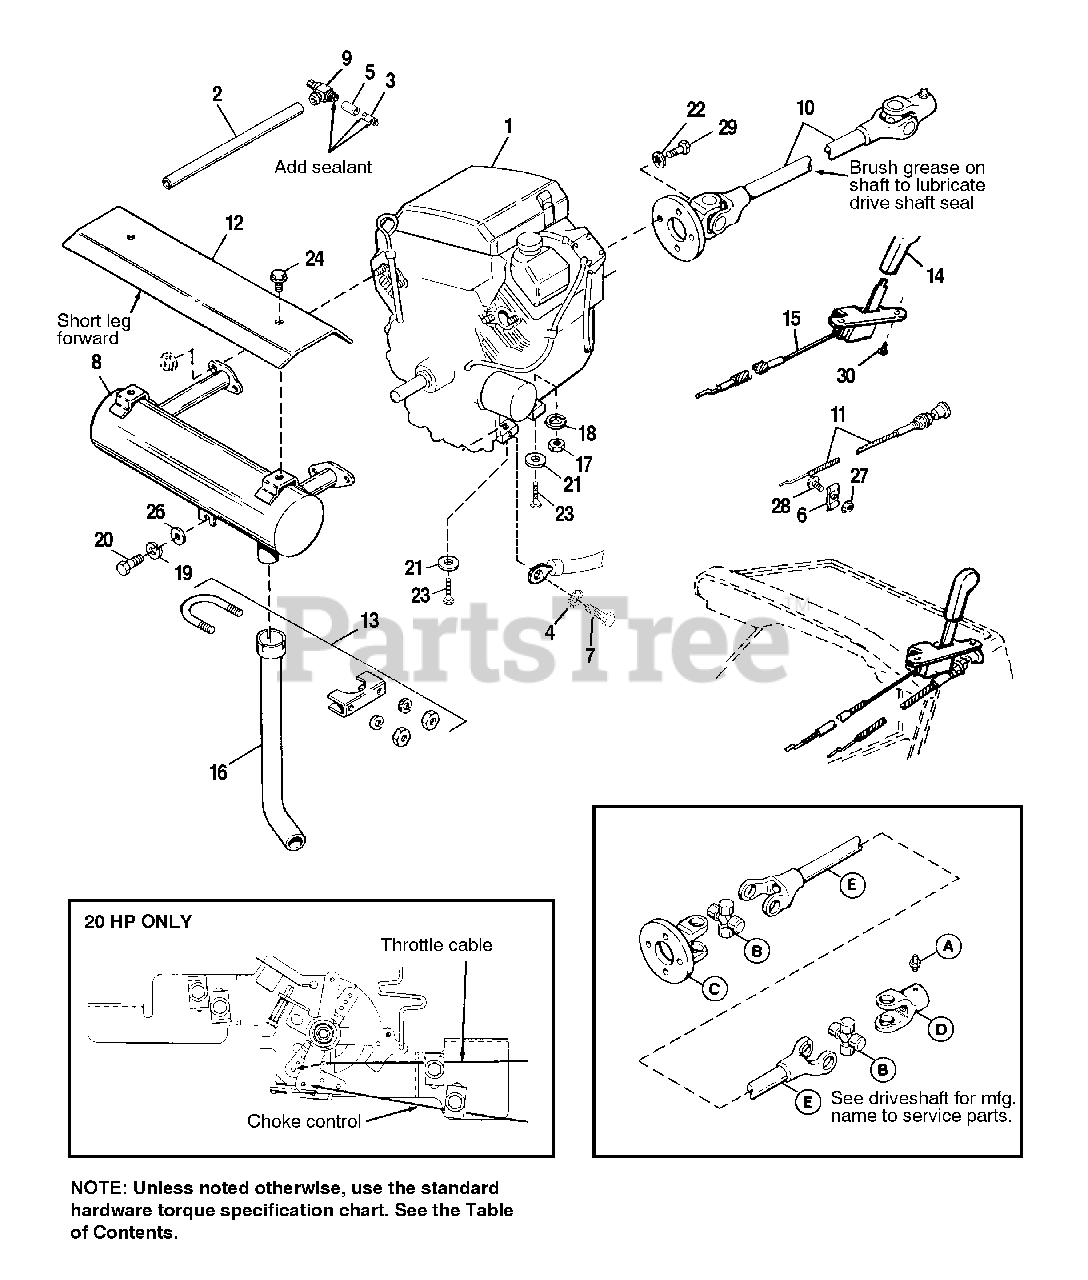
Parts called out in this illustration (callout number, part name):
1	ENGINE, 20 HP, Kohler
2	HOSE, Oil, Drain
3	NIPPLE, Pipe, 3/8 x 1
4	WASHER, External Tooth, 3/8
5	COUPLING, Pipe, Straight
6	CLIP, Double
7	BOLT, Hex Hd., Flange, M8-1-1/4 x 20mm
8	MUFFLER, Exhaust
9	VALVE, Shut Off
10	DRIVE SHAFT ASSY.
11	CONTROL, Choke w/Knob
12	HEAT SHIELD, Muffler
13	CLAMP, Exhaust
14	KNOB, Throttle
15	THROTTLE CONTROL ASSY.
16	ELBOW, Exhaust
17	NUT, Hex, 3/8-16
18	LOCKWASHER, 3/8
19	LOCKWASHER, 7/16
20	CAPSCREW, Hex Hd., 7/16-14 x 1
21	WASHER, 13/32 x 1 x 1/8
22	LOCKWASHER, Internal Tooth
23	CAPSCREW, Hex Hd., 3/8-16 x 2
24	SCREW, Hex Hd., Taptite, 5/16-18 x 1/2
26	WASHER, 15/32
27	NUT & WASHER ASSY., #10-32 (KEPS)
28	SCREW, Truss Hd. (Phillips), #10-32 x 1/2
29	CAPSCREW, Hex, Socket Hd., M8 x 1-3/4 x 20mm
30	SCREW, Plastite, 1/4-10 x 1/2
A	FITTING, Lube
B	CROSS & BEARING KIT (Neapco)
B	CROSS & BEARING KIT (Weasler)
C	YOKE & FLANGE ASSY. (Neapco)
C	YOKE & FLANGE ASSY. (Weasler)
D	YOKE (Neapco)
D	YOKE (Weasler)
E	YOKE & TUBE ASSY. (Neapco)
E	YOKE & TUBE ASSY. (Weasler)
